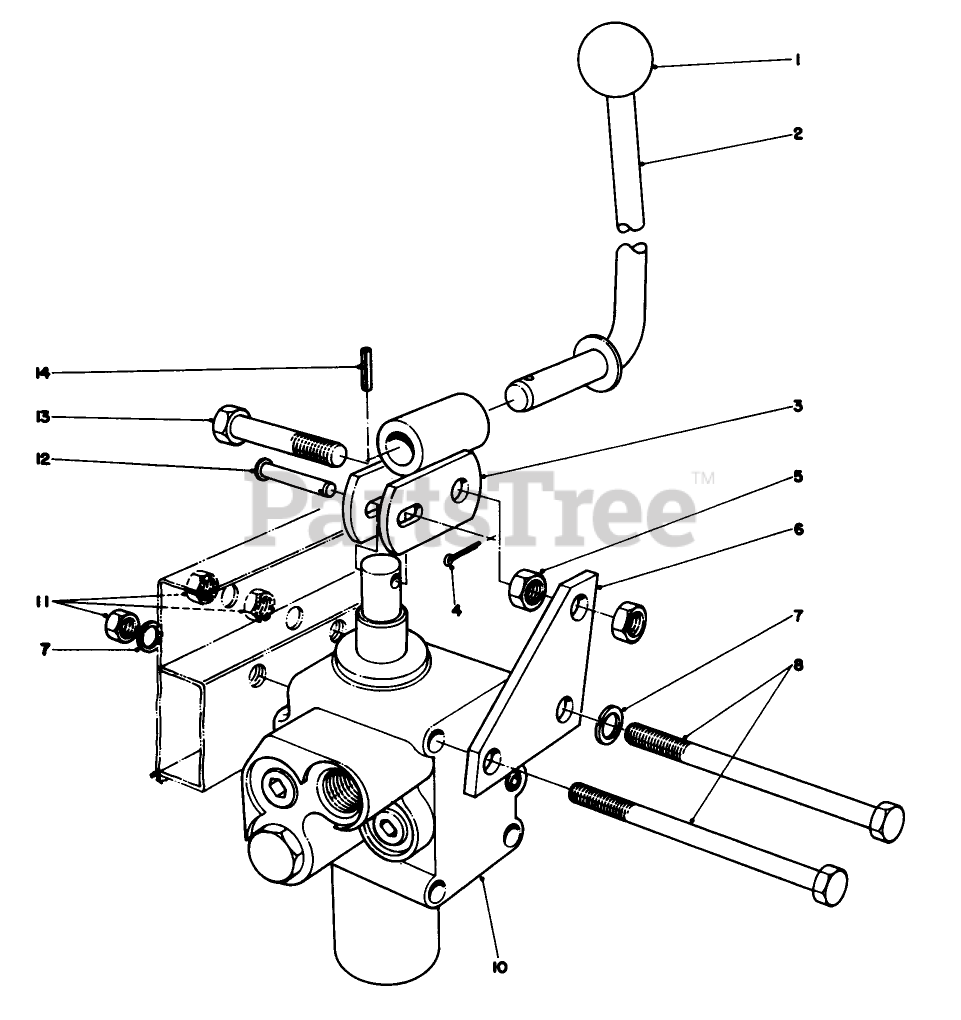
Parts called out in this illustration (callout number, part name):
1	KNOB-CONTROL
2	Valve Lever
3	Valve Lever Link
4	PIN-COTTER
5	NUT-JAM
6	Bolt-Wheel
7	WASHER-LOCK
8	SCREW-HH
10	Valve
11	NUT-HEX
12	PIN-CLEVIS
13	SCREW-HH
14	PIN-ROLL
